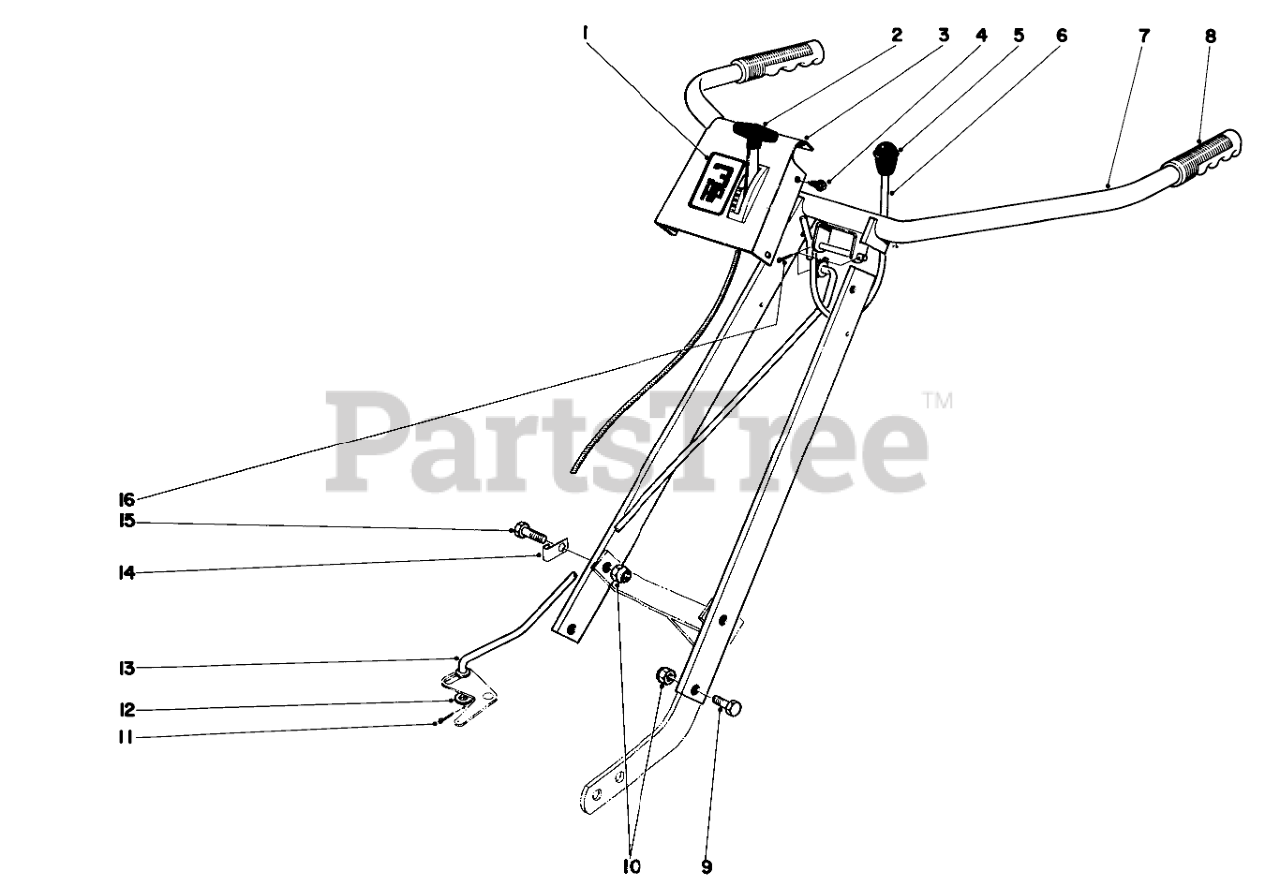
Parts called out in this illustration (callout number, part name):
1	Decal
2	Throttle
3	Cover Handle
4	10-16 X 3/8 THDG SCREW
5	Knob
6	Shift Lever
7	Handle Bar
8	Handle Grip
9	SCREW-HH
10	NUT-LOCK, CONE
11	PIN-COTTER
12	Washer
13	Clutch Rod
15	SCREW-HH
16	PIN-COTTER
